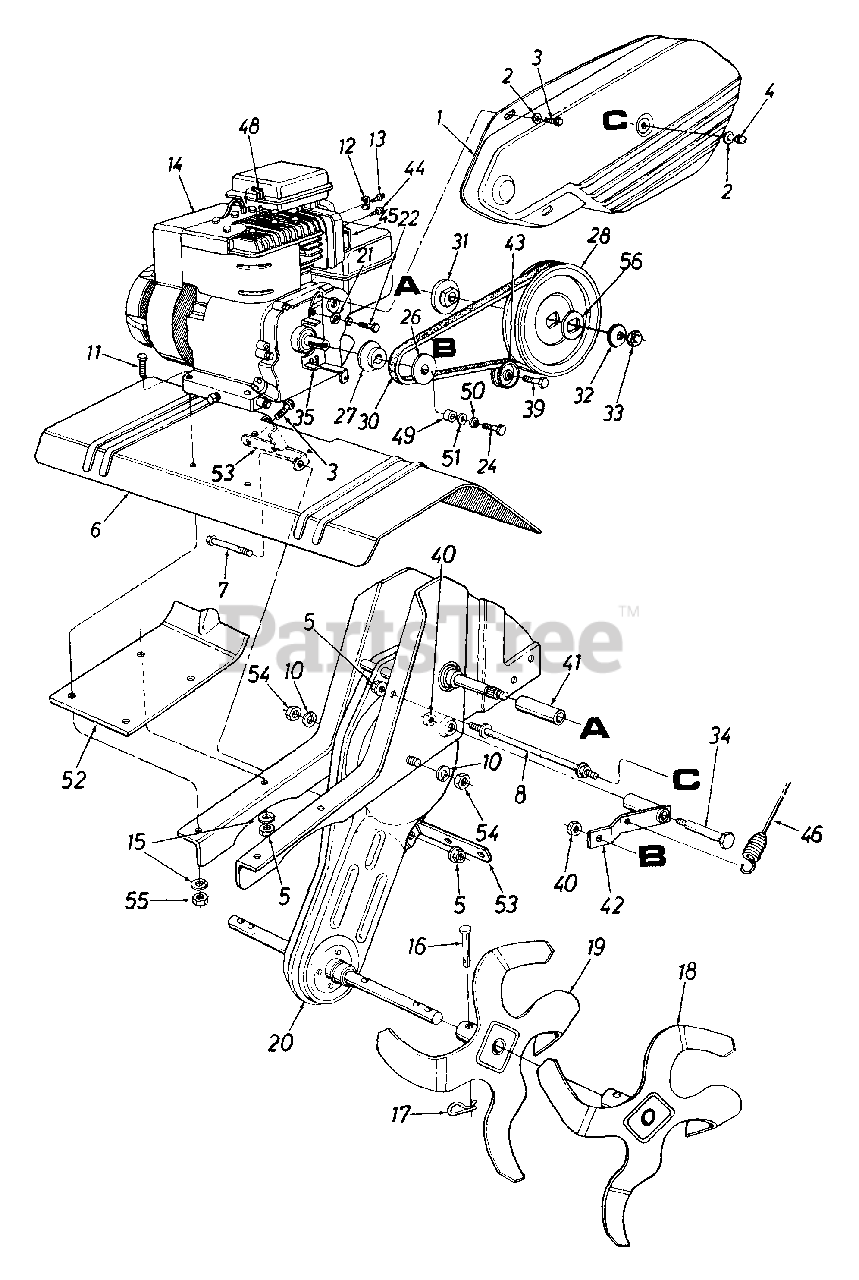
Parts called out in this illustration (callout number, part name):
2	Fl-Wash. .266" I.D. x .625" O.D.
3	Hex Wash. Md. TT-Tap Scr. 1/4-20 x .5" Lg.
4	Hex L-Stop Nut 1/4-28 Thd,
5	Hex Flange Top L-Nut 5/16-18 Thd. (Gr. 5)
8	Belt Cover Bolt
10	L-Wash. 7/16" I.D.
11	Hex Bolt 5/16-18 x 1.75" Lg.
12	Casing Clamp
13	Hex Sems Scr. #10-32 x .62" Lg.
14	Engine, 5 H.P.
15	Spec. L-Nut 5/16" I.D.
16	Clevis Pin .375" Dia. x 1.75" Lg.
17	Internal Cotter Pin
20	Chain Case Ass'y. Comp.
21	L-Wash. 5/16" I.D."
22	Hex Bolt 5/16-24 x .5" Lg.
24	Hex Bolt 3/8-24 x 1.25" Lg.
26	1/2" "V"-Pulley Half
27	1/2" "V"-Pulley Half
28	Fl-Pulley 6" Dia.
30	"V"-Belt
31	Pulley Mounting Adapter
32	Bell-Wash. .535" I.D. x 1.5" O.D.
33	Hex Jam Nut 1/2-20 Thd. (Gr. 5)
34	Shld. Bolt .498" Dia. x 1.45" Lg.
39	Hex Cap Bolt 3/8-16 x 1.25" Lg.
40	Hex Cent. Jam Nut 3/8-16 Thd.
41	Spacer .64" I.D. x 2.4" Lg.
42	Tine Idler Brkt. Ass'y.
43	Fl-Idler 2" O.D.
44	Hex Self-Tap Scr. 08-32 x .38" Lg.
45	Muffler Deflector
46	Clutch Control Cable
48	Spark Plug Boot
49	Spacer .758" I.D. x .99" O.D.
50	L-Wash. 3/8" I.D.
51	Fl-Wash. 3/8" I.D. x 1" O.D.
54	Hex Nut 7/16-20 Thd.
55	Hex Nut 5/16-18 Thd. (Gr. 5)
56	Bearing Retaining Washer
